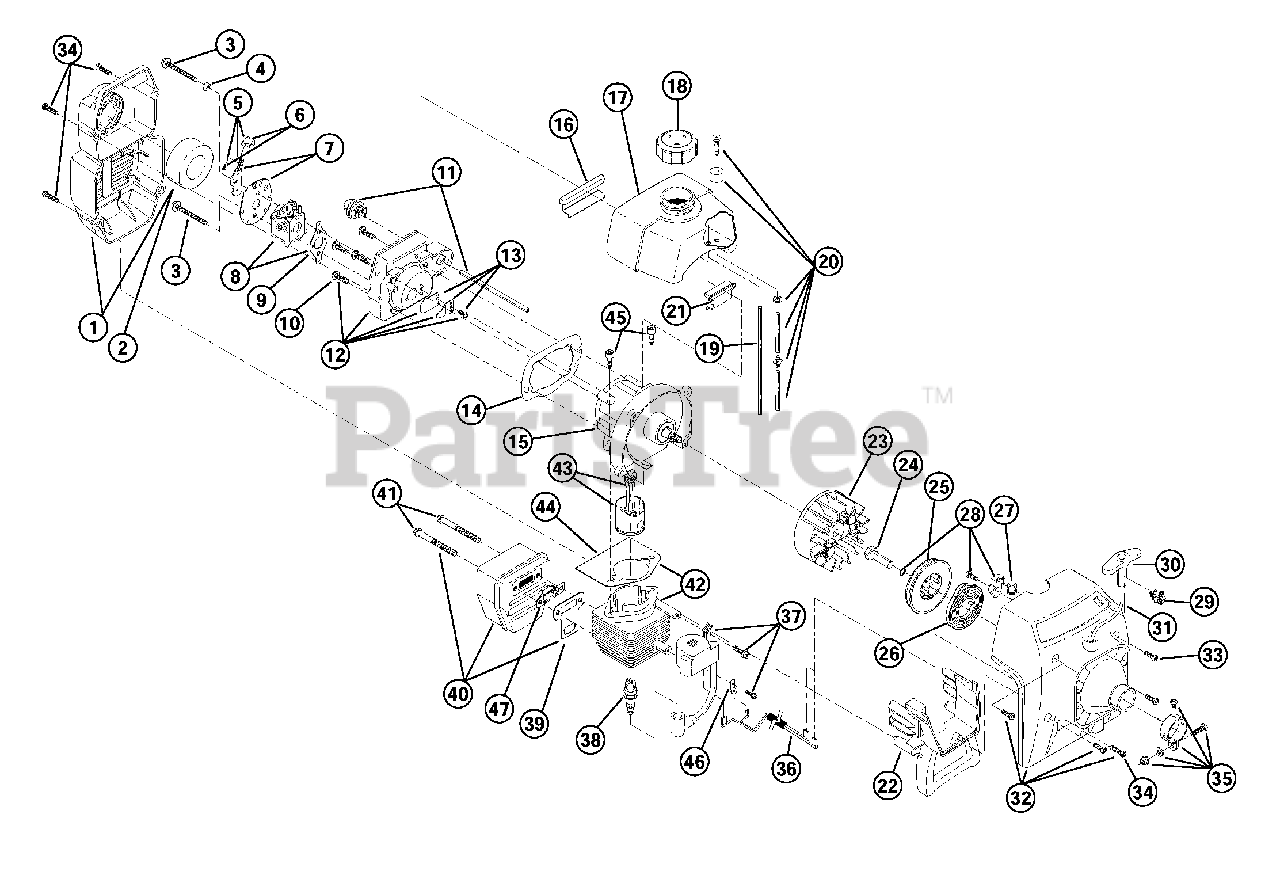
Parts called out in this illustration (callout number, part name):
1	Air Cleaner/Muffler Cover Assembly
2	Air Cleaner Filter
3	Carburetor Mounting Screw Assembly
4	Wavey Washer
5	Choke Lever Assembly
6	Choke Knob and Screw
7	Choke Lever and Plate
8	Carburetor Assembly
9	Carburetor Gasket
10	Carb Mount Screw
11	Primer and Hose Assembly
12	Carb Mount Assembly
13	Reed Assembly
14	Carburetor Mount Gasket
15	Crank Case Service Assembly
16	Rear Mounting Pad
17	Fuel Tank Assembly
18	Fuel Cap Assembly
19	Fuel Return Line
20	Fuel Line Assembly
21	Front Mounting Pad
22	Shroud Extension and Stand
23	Flywheel Assembly
24	Square Nut Drive
25	Recoil Pulley Assembly
26	Recoil Spring
27	Rope Guide
28	Pulley Retainer Assembly
29	Switch Assembly
30	Pull Handle
32	Starter Housing Assembly
33	Housing Screw
34	Cover Screw
35	Upper Clamp Assembly
36	Wire Lead
37	Module Assembly
38	Spark Plug
39	Exhaust Gasket
40	Muffler Assembly
41	Muffler Mounting Bolt Assembly
42	Cylinder Assembly
43	Piston and Rod Assembly
44	Cylinder Gasket
45	Cylinder Bolt
46	Ground Tab
47	Spark Arrestor
